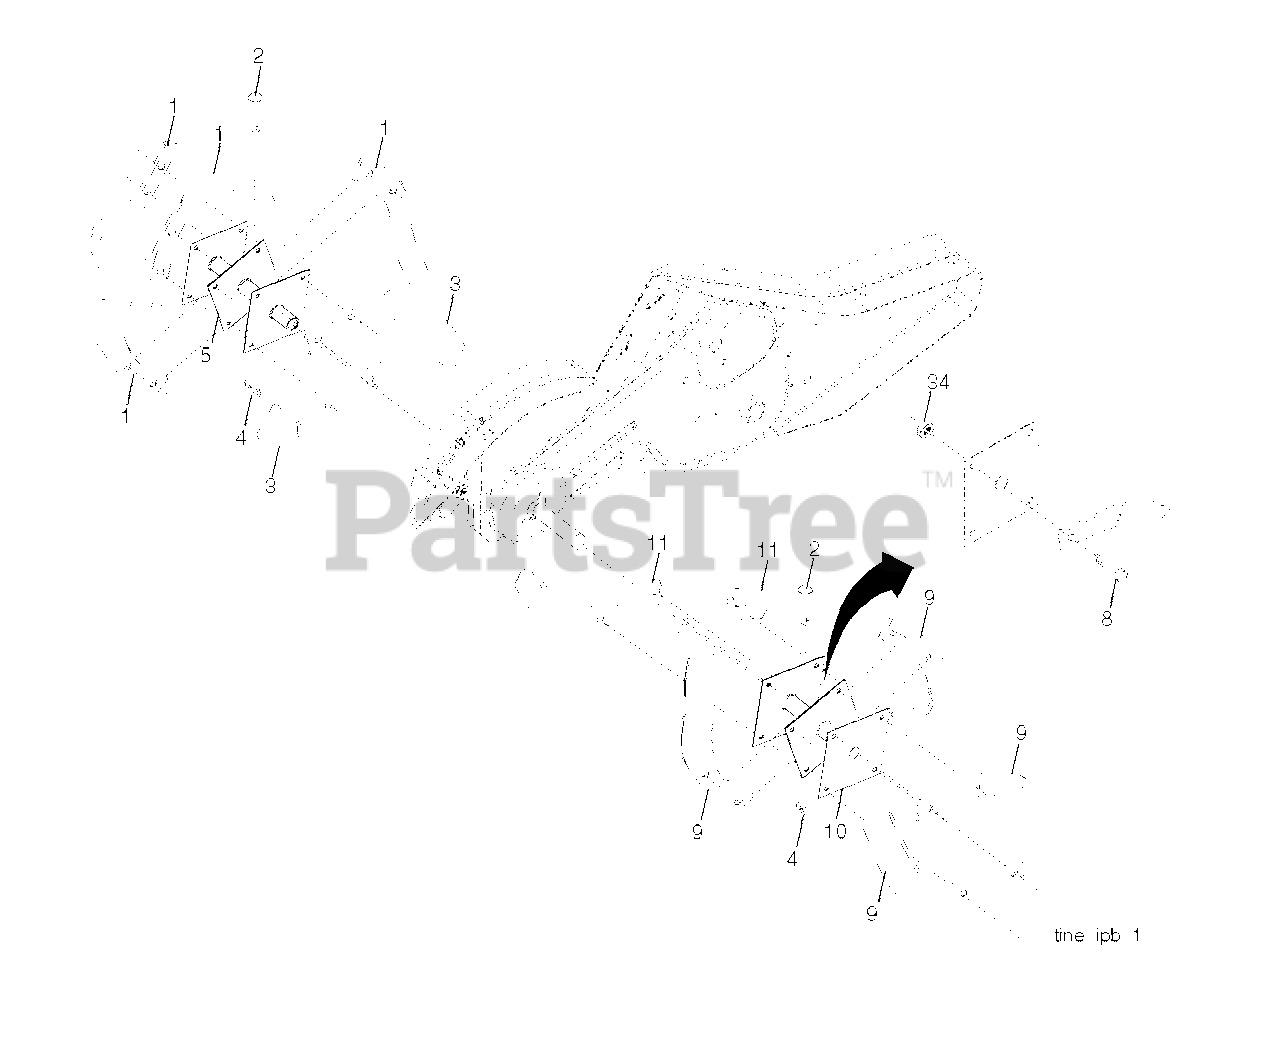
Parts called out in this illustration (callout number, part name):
1	TINE TI
2	CLEVIS PIN
3	TINE.LH.12"
4	SPRING RETAINER
5	HUB & PLATE ASM LH
8	BOLT.HEX.001X20.37-24X1.ZINC
9	TINE TI
10	HUB & PLATE ASM RH
11	TINE.RH.12"(72R)
34	NUT CROWNLOCK 3/8-24
